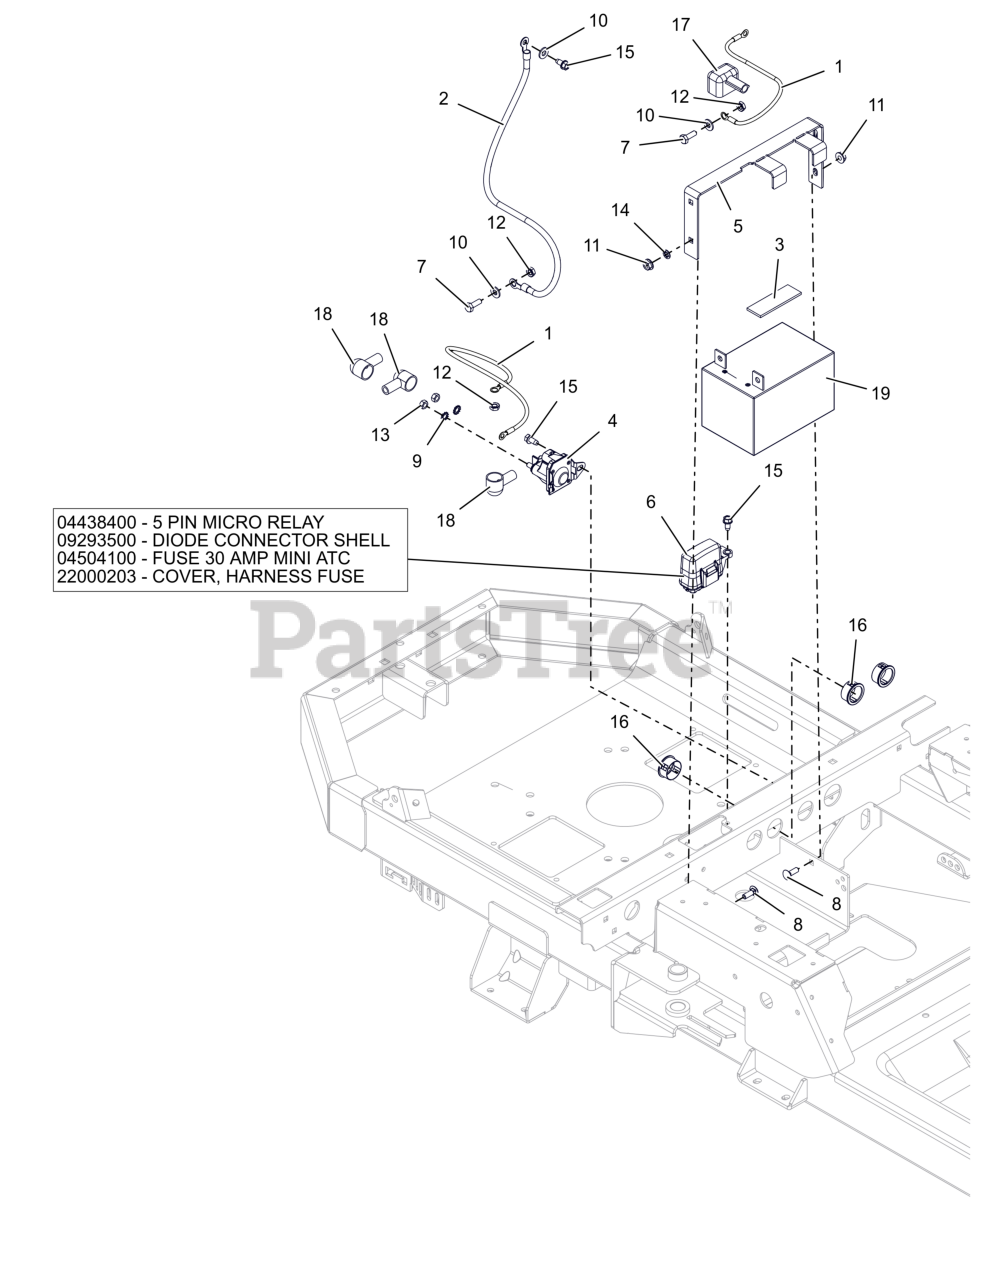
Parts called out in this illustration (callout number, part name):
1	CABLE,POS W/2 1/4 RING 15.0 LG
2	CABLE-NEGATIVE BATTERY 24.00"
3	PAD,RBR 1.0"X3.0" W/ADHESIVE
4	SOLENOID, STARTER (SEALED)
5	BRKT, BATTERY HOLD-DOWN (BLACK)
6	HARNESS, WIRE
6	RELAY,MICRO5 TERML W/RESISTOR
6	DIODE, CONNECTOR SHELL
6	FUSE30 AMP MINI ATC
6	COVER, FUSE
7	BLT, HEX .25-20X.75 G5 ZCC
8	BLT, RHSN .25-20X.750 G5 ZCC
9	WSHR,LK-EXT.262X.502X.026 ZCC
10	WSHR,FLT .281X.625X.065 ZCC
11	NUT-LK-TOP-FLG .250-20 GF ZCC
12	NUT-KEPS .250-20 ZCC
13	NUT-STD M6-1.0 ZCC
14	NUT-PUSH .25X.50 O.D.
15	SCR-TAP .25-20X.50 HWH ZCC
16	BSHG, PANEL SNAP .937X1.11X.56
17	INSULATOR
18	BOOT, EYELET TERMINAL
19	BATTERY, 12V 12AH -190CCA
